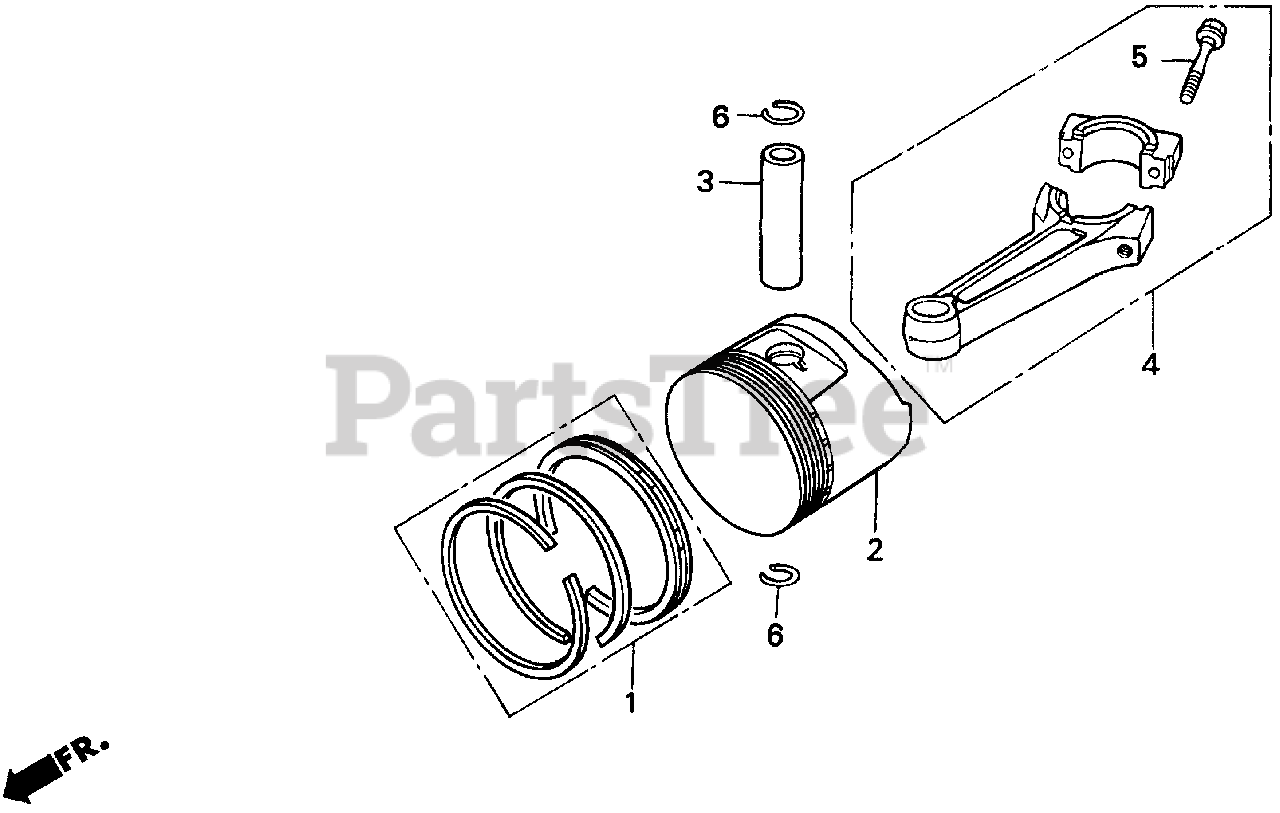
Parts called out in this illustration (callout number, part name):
1	RING SET, PISTON (STD)
1	RING SET, PISTON (OS 0.25)
1	RING SET, PISTON (OS 0.50)
1	RING SET, PISTON (0.75) (NIPPON)
2	PISTON (STD)
2	PISTON (OS 0.25)
2	PISTON (OS 0.50)
2	PISTON (0.75)
3	PIN, PISTON
4	ROD ASSY., CONNECTING
4	ROD ASSY., CONNECTING (US 0.25)
5	BOLT, CONNECTING ROD
6	CLIP, PISTON PIN (20MM)
